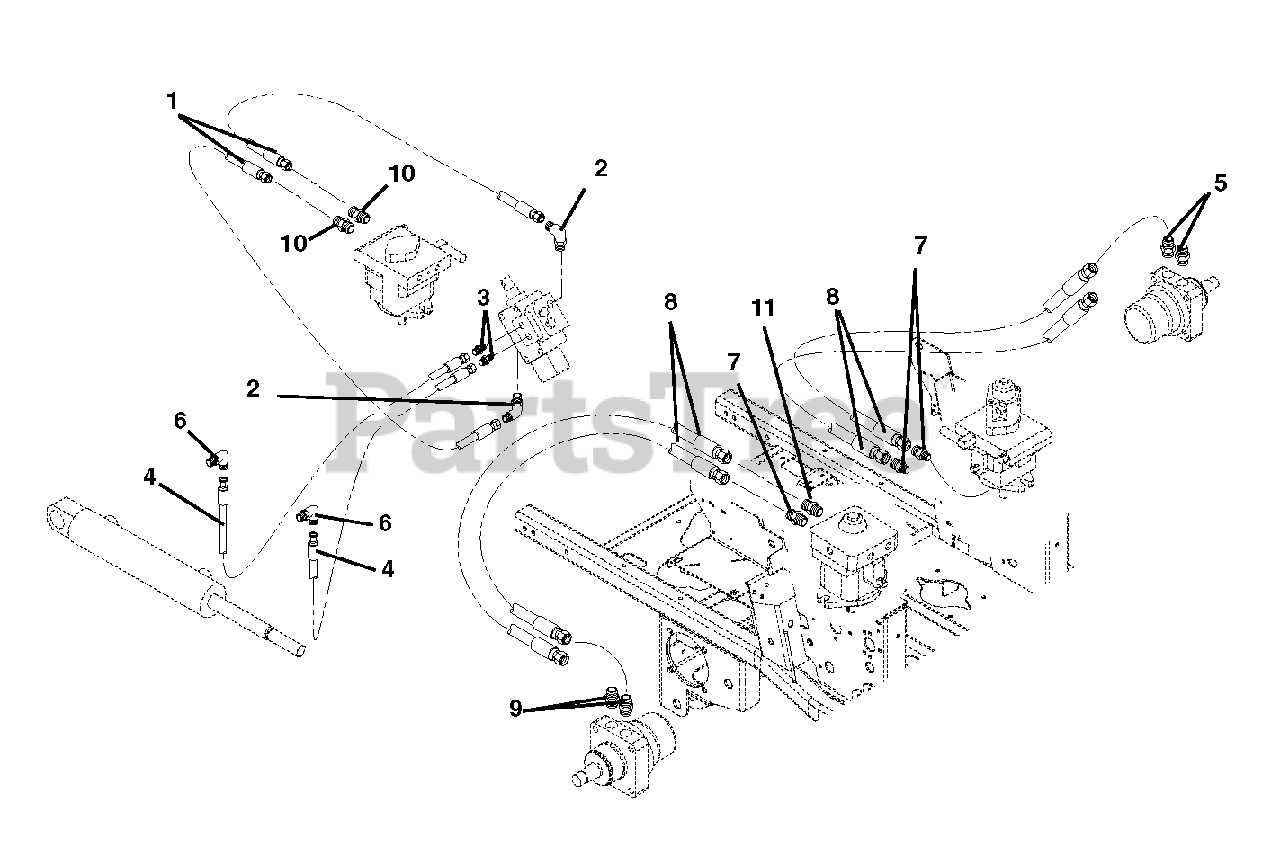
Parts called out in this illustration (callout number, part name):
1	Hose, Hydraulic (992150, 154, 159, 163, 164, 166, 167, 168, 170, 172)
2	Hydraulic, Fitting Elbow (992150, 154, 159, 163, 164, 166, 167, 168, 170, 172)
3	Adapter (4-6F5OLO) (992150, 154, 159, 163, 164, 166, 167, 168, 170, 172)
4	Hose, Hydraulic (992150, 154, 159, 163, 164, 166, 167, 168, 170, 172)
5	Fitting, Hyraulic Straight (8-10 F5OLO-S) (992150, 154, 159, 163, 164, 166, 167, 168, 170, 172)
6	Fitting, Hydraulic (4 C5OLO) (992150, 154, 159, 163, 164, 166, 167, 168, 170, 172)
7	Adapter, Face Seal 8 x 8 .50 O-Ring
8	Hose, Hydraulic .50
9	Adapter, Hydraulic Steel (M10 O-M8F)
10	Fitting, Hydraulic (4 F5OLO) (Supplied with pump) (992150, 154, 159, 163, 164, 166, 167, 168, 170, 172)
11	Fitting,Hydraulic 45 Degree M8F-M80
